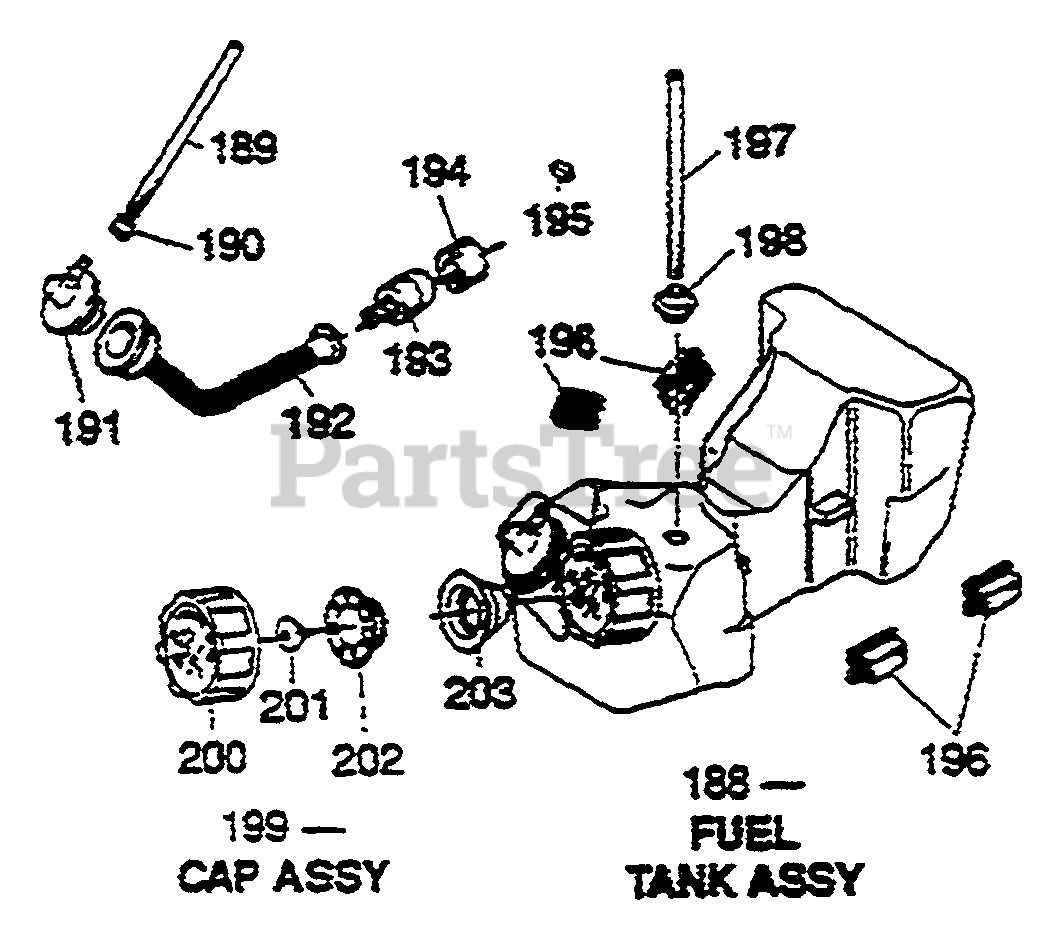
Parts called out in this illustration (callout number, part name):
188	FUEL TANK ASSY
189	TUBE, FUEL
192	HOSE, SUCTION
193	FILTER, FUEL
197	TUBE, FUEL
199	TANK CAP ASSY
200	CAP, TANK
201	VALVE, BREATHER
